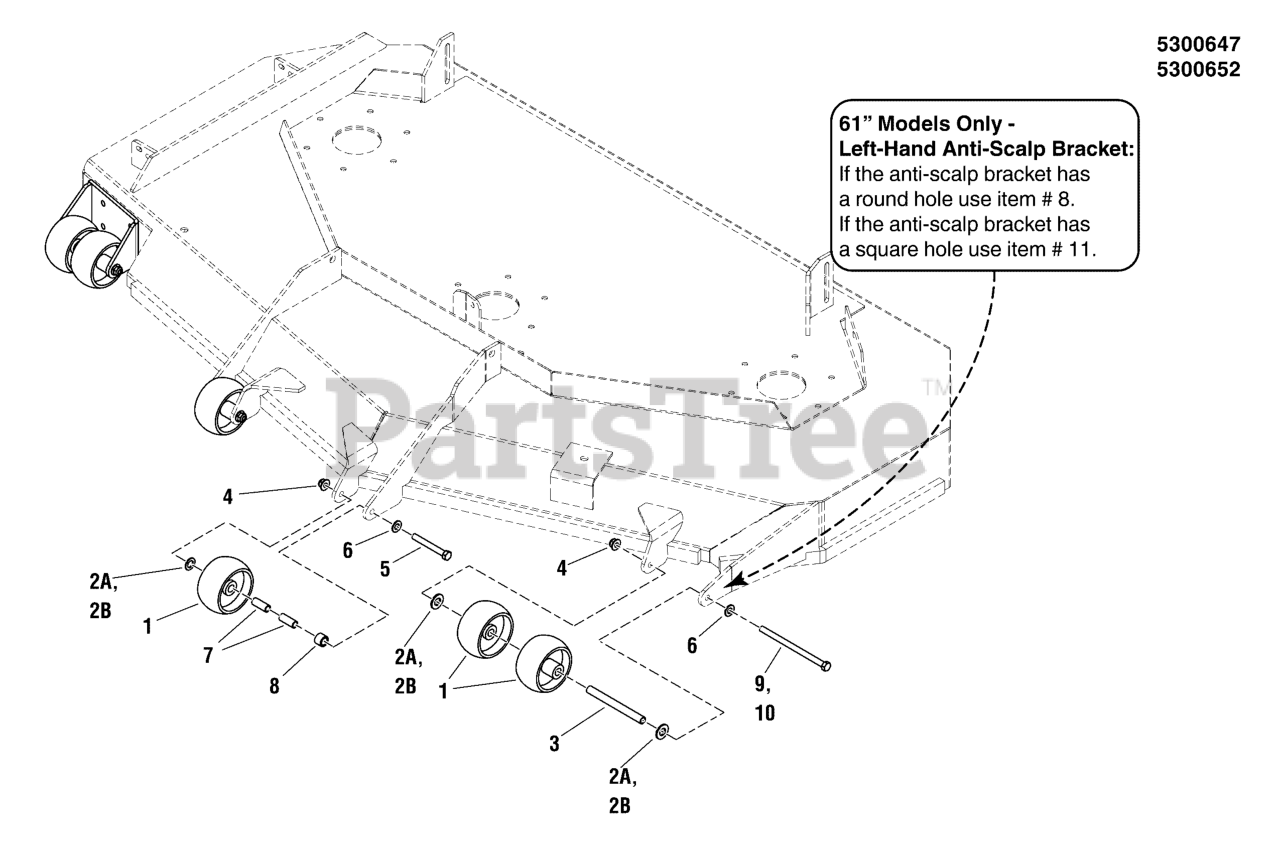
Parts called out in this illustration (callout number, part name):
1	WHEEL- 2.00 WIDE 3.88 DIA 0.531ID POLY
3	SPACER, .38 X .50 X 5.06
4	NUT, 3/8-16 HEX SIDE LOCK
5	BOLT, 3/8-16 X 3" GD5 CZ
6	WASHER, 3/8 SAE
7	SPACER, .38 X .50 X 1.25, CZ
8	SPACER, .51 X .75 X .56
9	BOLT, 3/8-16 X 6" GD5 CZ
10	BOLT, CARRIAGE, 3/8-16X6, GD5, CZ
